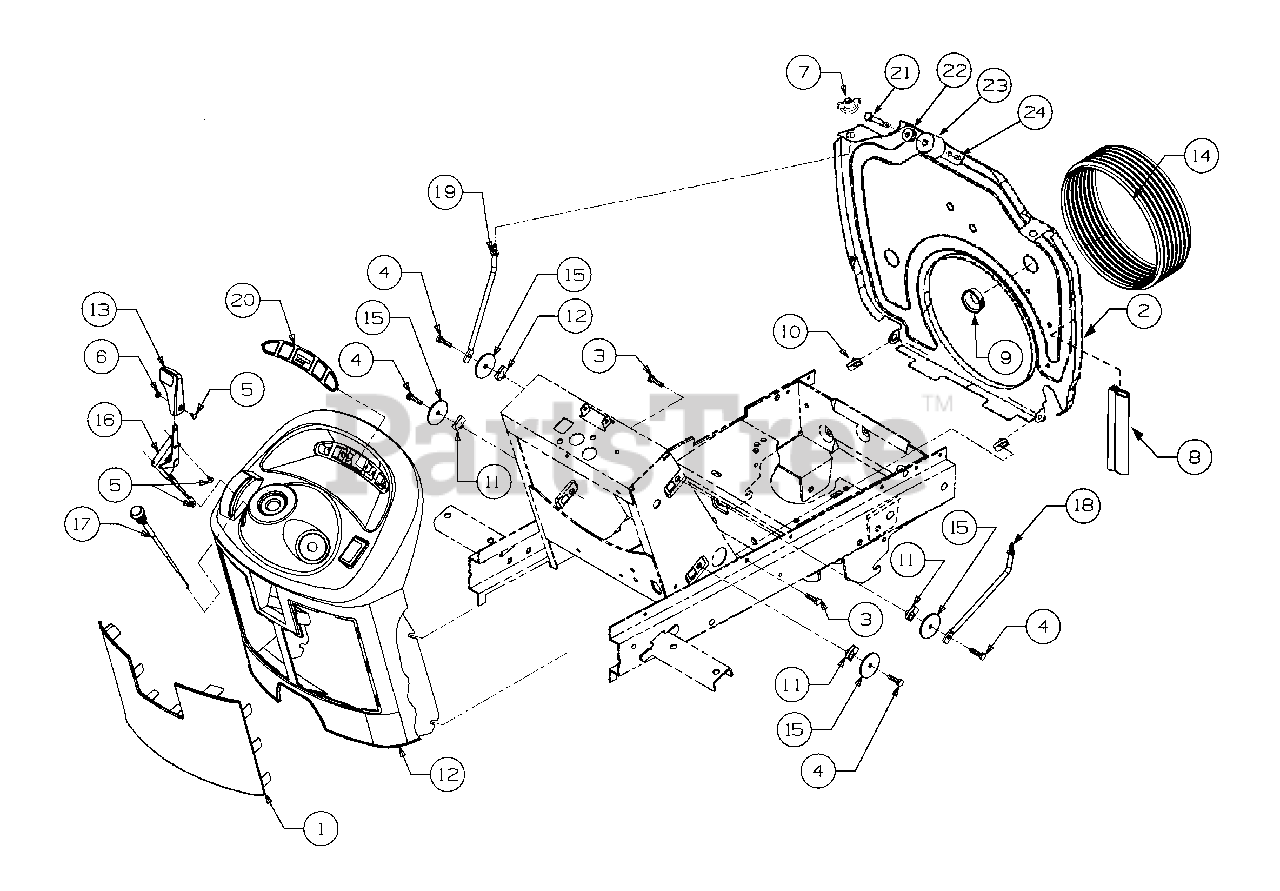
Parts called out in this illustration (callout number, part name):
1	Screen, Intake Dash
2	Bulkhead, Lower
3	Screw, Hex Cap, 1/4-20 x .625
4	Screw, Hex Cap, 1/4-20 x 1.0
5	Screw, Cross Rec Trus, #8-32 x .38
6	Nut, #8-32
7	Nut, Wing w/Bell Washer 1/4-20
8	Seal, Push On Trim
9	Bushing, Snap, 7/8 ID
10	Nut, U-Type Speed, 1/4-20
11	Nut, U-Clip, 1/4-20
12	Panel, Dash
12	Graphic, Ignition Switch
13	Knob, Throttle
14	Boot, Intake
15	Washer, Flat, .285 x 1.75 x .10
16	Control, Throttle 28.75 LG x .70 EXT
16	Control, Throttle 22 LG x .70 EXT
17	Control, Choke 31.13 LG x 2.0 EXT
17	Control, Choke 30.5 LG x 7.0 EXT
17	Control, Choke 24.5 LG x 2.0 EXT
18	Rod, RH Mounting
19	Rod, LH Mounting
20	Label, Dash
21	Screw, Hex Cap,1/4-20 x 1.75 GR5
22	Washer, Flat, .283 x .75 x .030
23	Roller, Hood Latch
24	Nut, Hex Sems, 1/4-20
